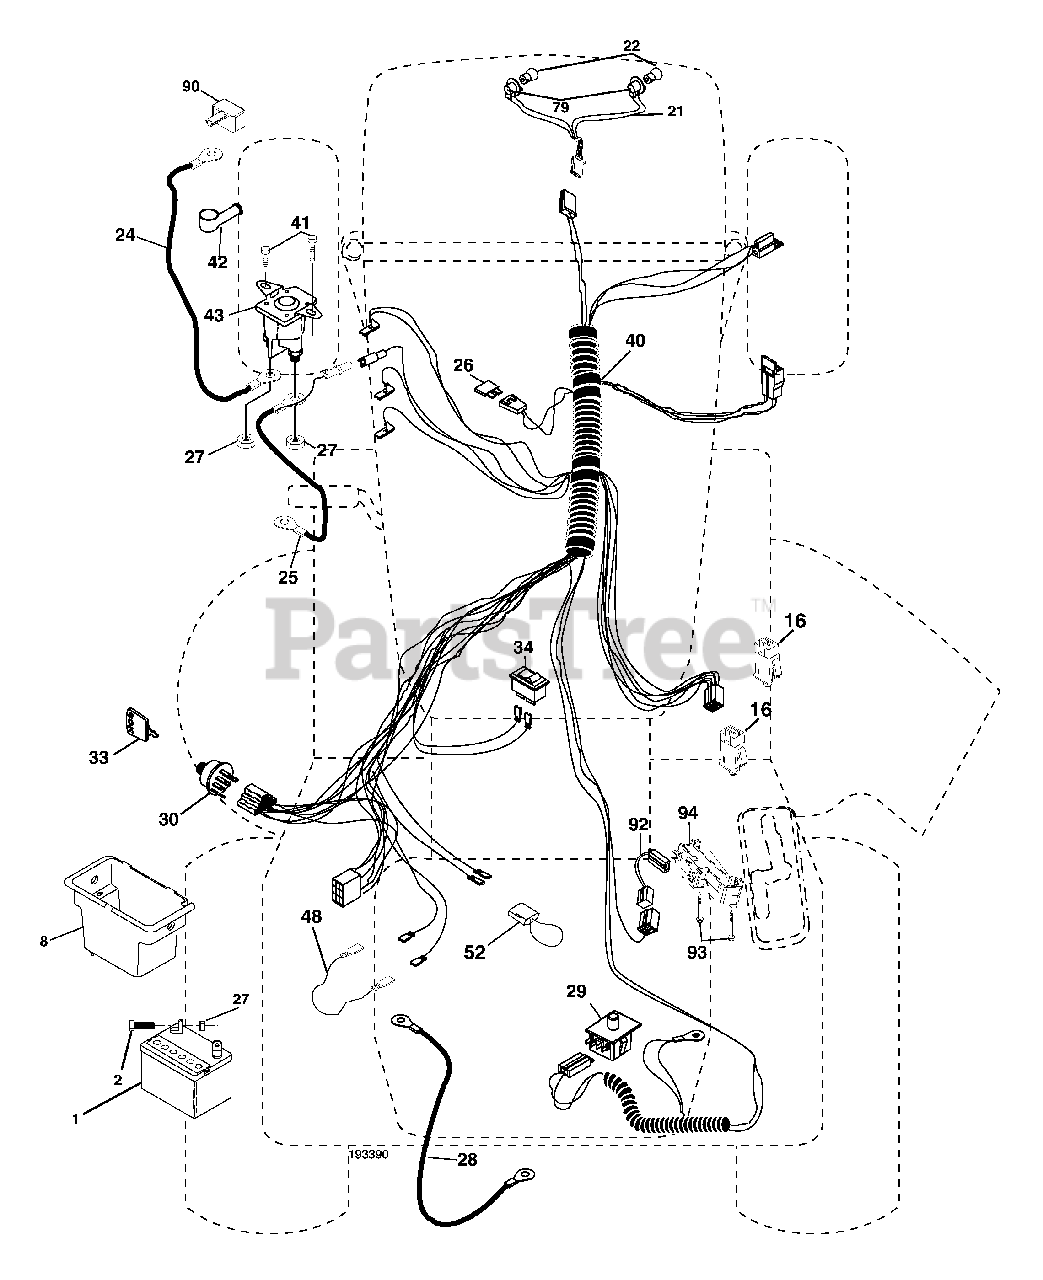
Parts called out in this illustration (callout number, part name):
1	Battery
2	Bolt Hex Hd 1/4-20 unc x 3/4
8	Box Battery
16	Switch Interlock
21	Harness Socket Light
22	Bulb, Light # 1156
24	Cable Battery
25	Cable Battery 6 Ga. Red w/16 wire 44"
26	Fuse
27	Nut Keps Hex 1/4-20 unc
28	Cable Ground 12" Blk 6 Ga.
29	Switch
30	Switch Ign
33	Key Ign Molded Generic
34	Switch Light/Reset
40	Harness Ign
41	Bolt Fin Hex 1/4-20 unc x 1/2
42	Cover Terminal Red
43	Solenoid
45	Ammeter Adapter
52	Protection Loop
79	Socket Asm
90	Cover Terminal
92	Harness Pigtail Reverse Switch
93	Screw Plastite 10-14 x 2.0
94	Module Reverse ROS
